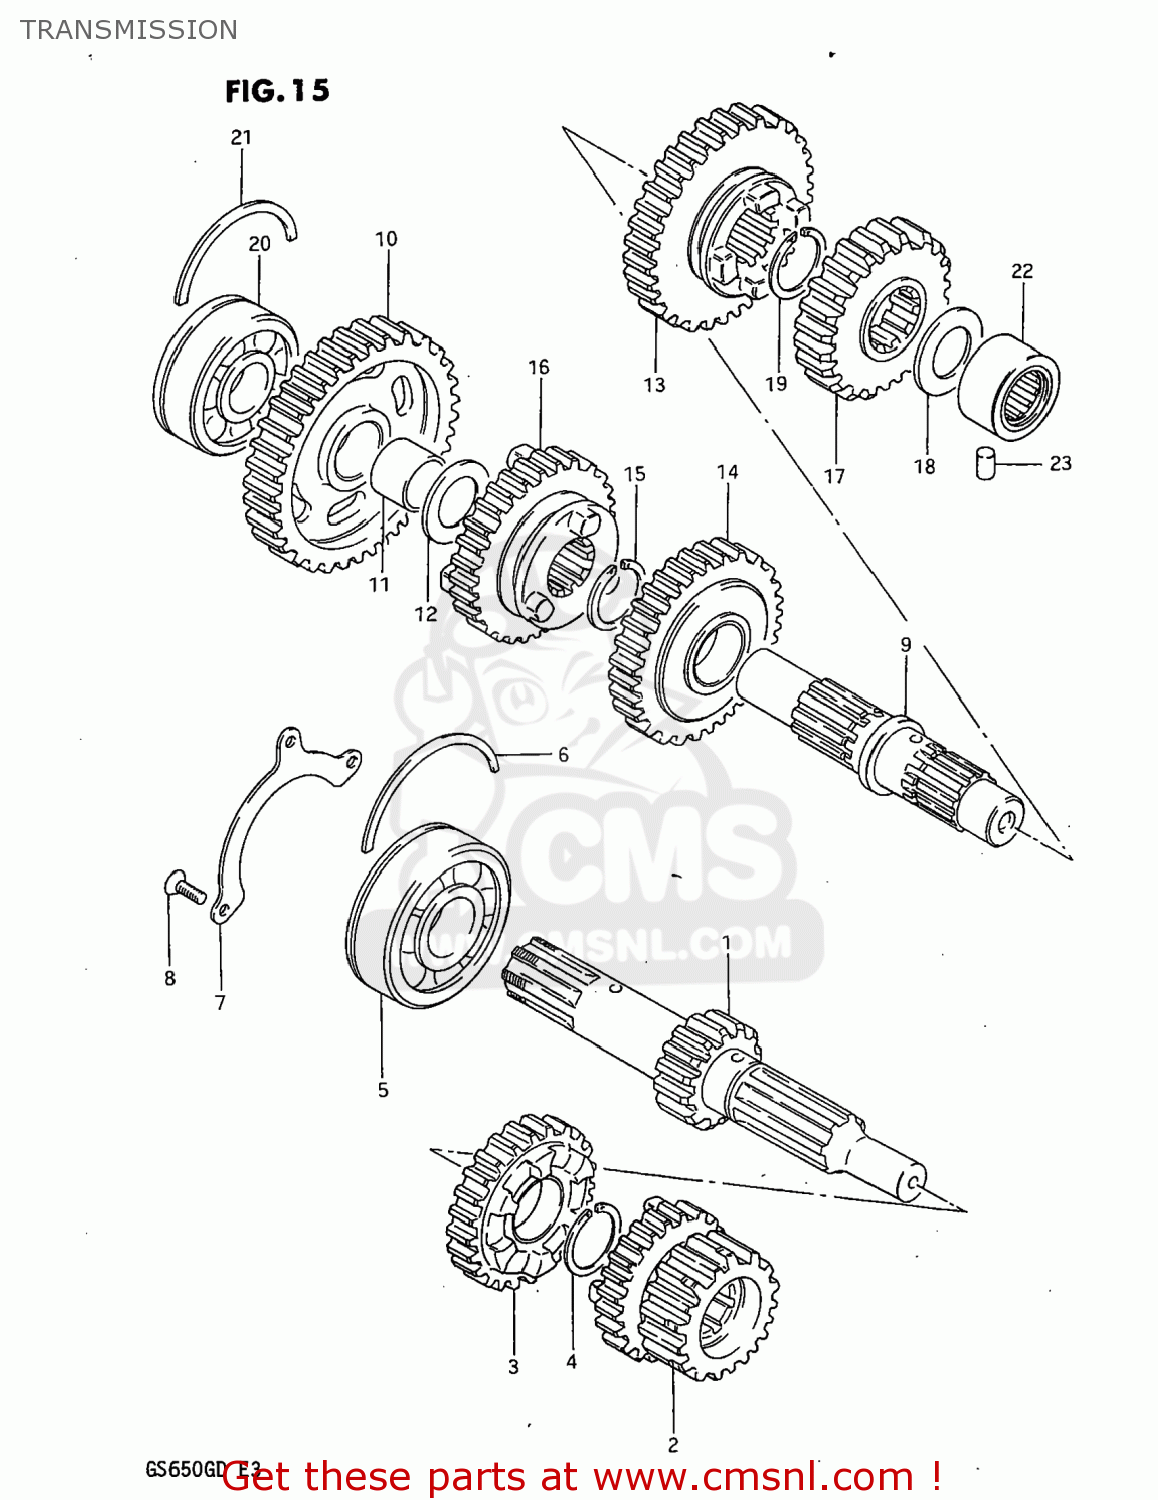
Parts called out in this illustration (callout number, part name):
1	SHAFT,COUNTER
2	GEAR,2ND & 3RD DRIVE
3	GEAR,FOURTH DRIVE
4	CIRCLIP
5	BEARING(25X62X17)
6	C-RING
7	RETAINER,CNTR SHAFT BEARING
8	SCREW
9	SHAFT,DRIVE
10	GEAR,FIRST DRIVEN
11	BUSHING
12	WASHER
13	GEAR,SECOND DRIVEN
14	GEAR,THIRD DRIVEN
15	CIRCLIP
16	GEAR,FOURTH DRIVEN
17	GEAR,REDUCTION(NT:24)
18	THRUST WASHER,REDUCTION
19	CIRCLIP
20	BALL BEARING 20X47X14
21	C RING
22	BEARING(20X34X16)
23	PIN
